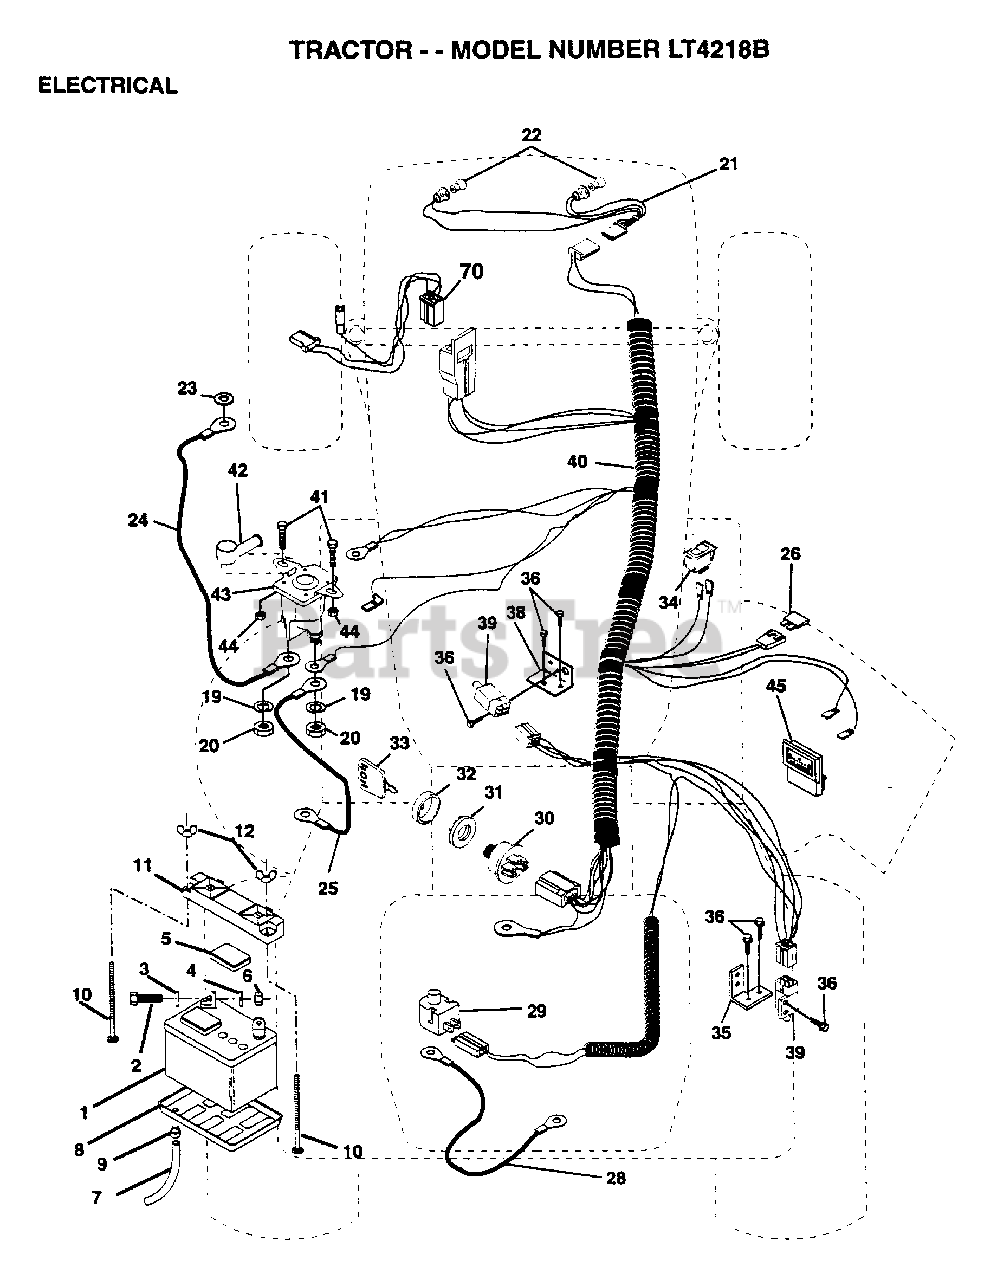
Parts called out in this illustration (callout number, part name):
2	BOLT LT
3	WASHER
4	LOCKWASHER
5	"CAP,BATTERY "
7	"DRAIN TU T, BATT"
8	"TRAY T, BATTERY"
9	HOSE CLAMP T
10	BOLT
20	NUT
21	"HARNESS,LIGHT SOC"
22	HEADLAMP BULB
23	LOCKWASHER
24	CABLE T
25	CABLE-BATTERY T
26	FUSE HYT
28	"CABLE T, BATTERY"
29	SWITCH SEAT
32	COVER KEY SWITCH
33	KEY MLD GEN DELTA
34	SWITCH LT
35	BRACKET LT
36	SCREW
38	BRACKET SWITCH IN
39	SWITCH INTERLOCKT
40	HARNESS IGNITION
41	BOLT HXHD FIN
44	NUT HXKEP 1/4X20
70	HARNESS ENG DUAL
